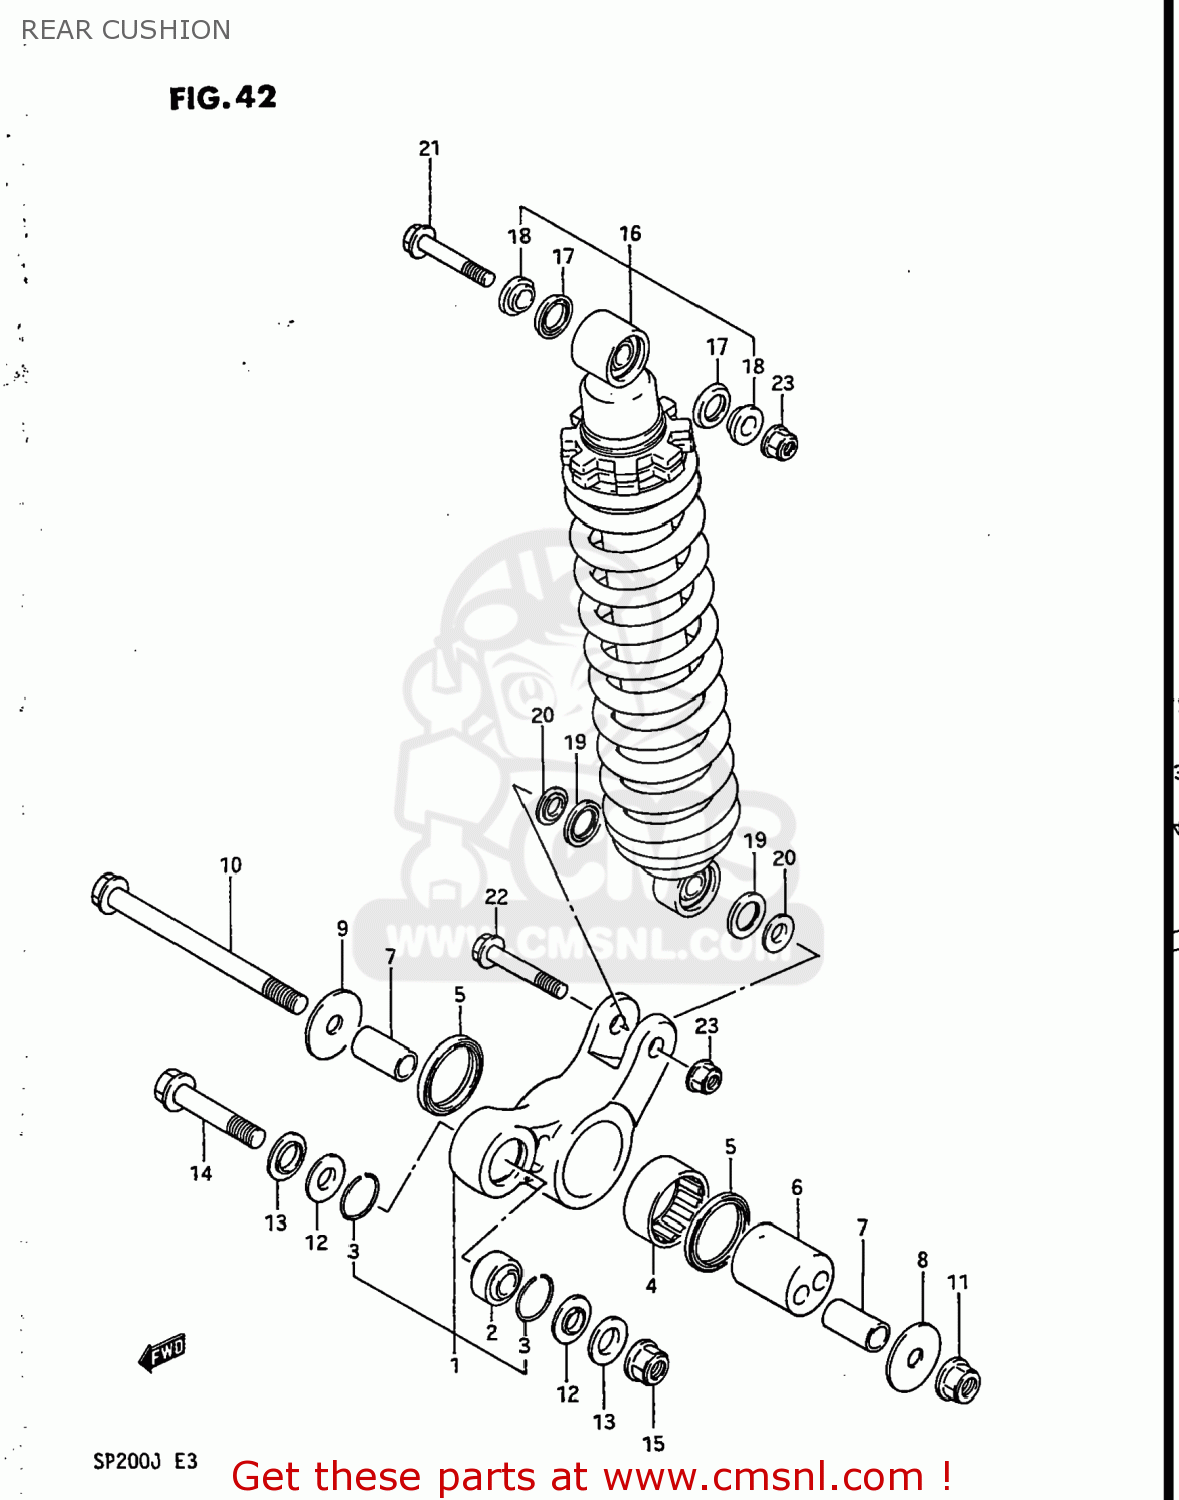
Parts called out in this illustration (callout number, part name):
1	LEVER SET,RR CUSHION
2	BEARING(12X26X16)
3	RING,STOPPER
4	BEARING(37X47X20)
5	SEAL,DUST
6	SPACER,RR SUSPENSION ECCENTRIC
7	SPACER,CUSHION LEVER SHAFT
8	WASHER(12X40X3)
9	WASHER,THRUST,R
10	SHAFT,REAR CUSHION LEVER
11	NUT 12MM
12	SEAL,RR CUSHION ROD DUST
13	SPACER,RR CUSHION ROD
14	BOLT,CUSHION LEVER FR
15	NUT 12MM
16	ABSORBER ASSEMBLY,REAR SHOCK
17	DUST SEAL
18	SPACER
19	SEAL,DUST
20	COLLAR
21	BOLT,REAR SHOCK ABSORBER
22	BOLT(10X48)
23	NUT
